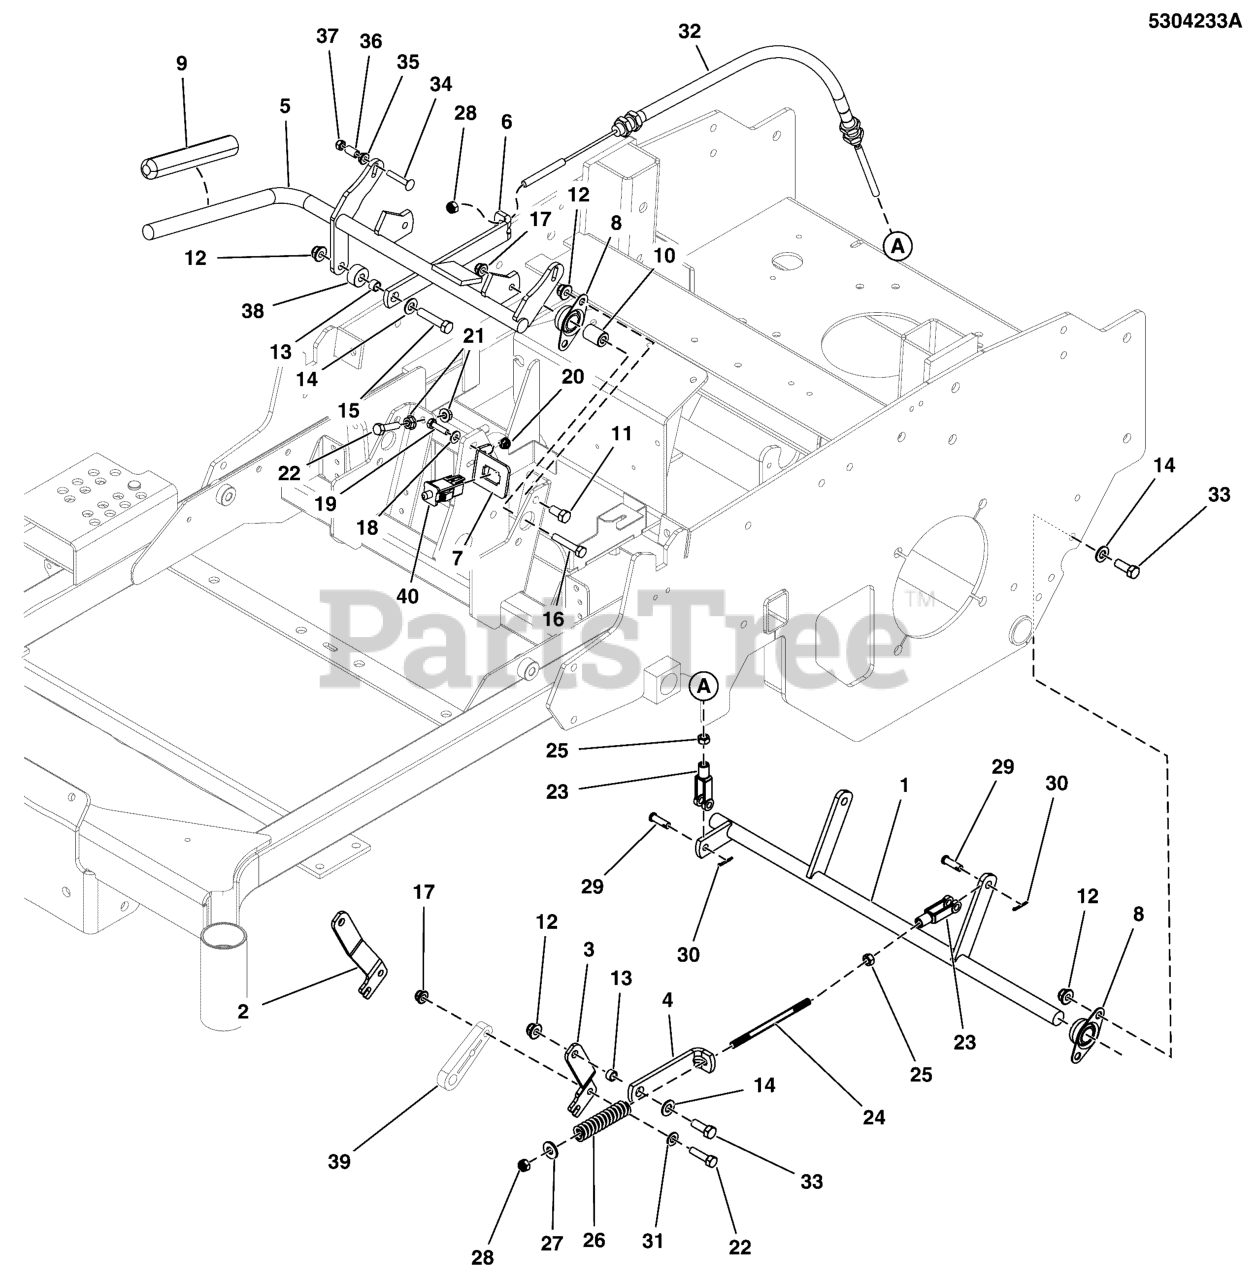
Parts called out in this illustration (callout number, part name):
1	WELD, BRAKE SHAFT, 150XT - BLK
2	PLATE, RIGHT BRAKE, 150XT - BLK
3	PLATE, LEFT BRAKE, 150XT - BLK
4	LINK, BRAKE LOCK, 150XT - BLK
5	WELD, BRAKE SHAFT - BLK
6	LINK, BRAKE LOCK - BLK
7	BRACKET, SWITCH MOUNT - BLK
8	BEARING, BRONZE FLANGE, 3/4"
9	GRIP, FOAM, 3/4 ID X 6 X .187
10	SPACER, .32 X .75 X 1.06, PM
11	BOLT, 3/8-16 X 3/4" GD5 CZ
12	NUT, 3/8 - 16 HEX NYLOCK FLANGE
13	SPACER, .38 X .50 X .31, CZ
14	WASHER, 3/8 SAE
15	BOLT, 3/8-16 X 1-1/2" GD5 CZ
16	BOLT, 5/16-18 X 1-3/4" GD5 YZ
17	NUT, 5/16-18 HEX NYLOCK FLANGE NUT
18	WASHER, 1/4 SAE
19	BOLT, 1/4"-20 X 3/4" GD5 YZ
20	NUT, 1/4-20 HEX SERR. FLANGE
21	NUT, 5/16-18 HEX SERRATED FLANGE (SMALL)
22	BOLT, 5/16-18 X 1-1/4" GD5 YZ
23	CLEVIS, 5/16-24, STEEL, CLEAR ZINC
24	ROD, BRAKE PULL, S150XT
25	NUT, Hex, 5/16-24
26	SPRING, COMP. 1/2 ID X .140 WIRE X 3.25
27	WASHER, 5/16" USS
28	NUT, 5/16-24 HEX NYLON LOCK
29	PIN, CLEVIS, 5/16 X 1, PLATED
30	PIN, 3/32 X 0.750, COT, ZINC/CLEAR
31	WASHER, 5/16" SAE
32	CABLE, PARKING BRAKE IS2000
33	BOLT, 3/8-16 X 1" GD5 CZ
34	BOLT, 1/4-20 X 1.500, GR5, SQ, ZINC/CLEAR
35	NUT, 1/4-20 HEX SERR. FLANGE
36	SPACER, .52 X .38 X .63, CZ
37	NUT, 1/4-20 HEX NYLON LOCK
38	SPACER, .39 X 1.00 X .25, PM, CZ
39	Refer to: Hydraulic Group
40	Refer to: Electrical Group
